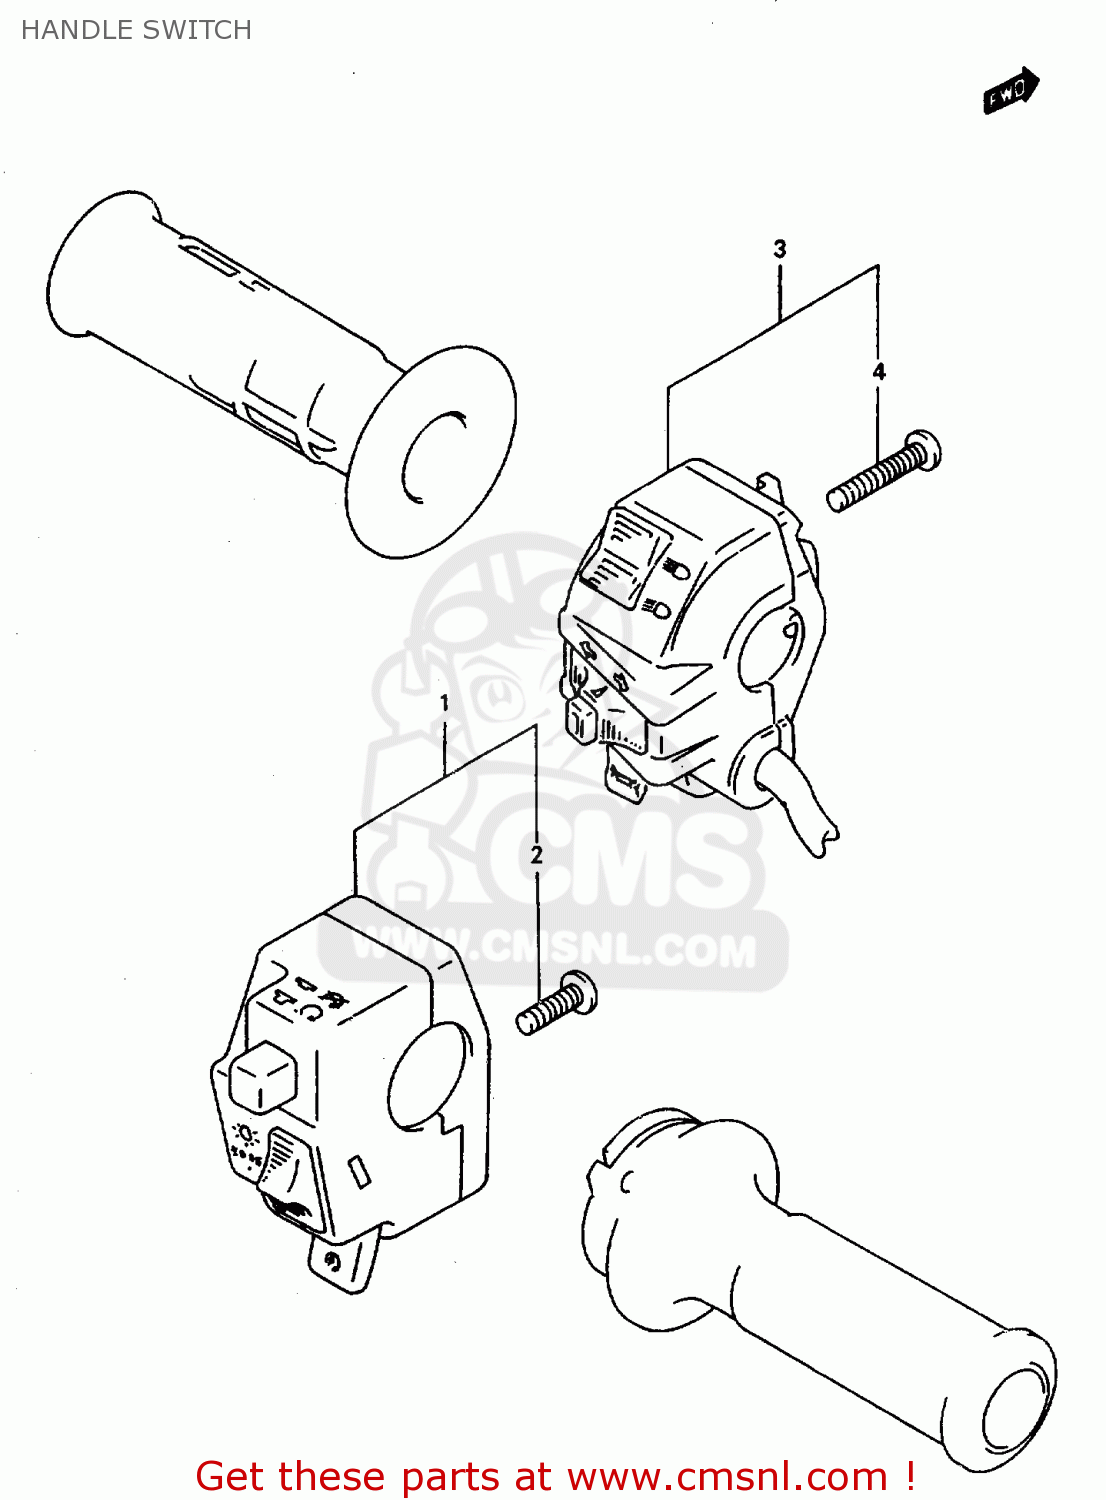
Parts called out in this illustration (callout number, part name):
1	SWITCH ASSY,HANDLE,R
2	SCREW
3	SWITCH ASSY,HANDLE,L
4	SCREW
